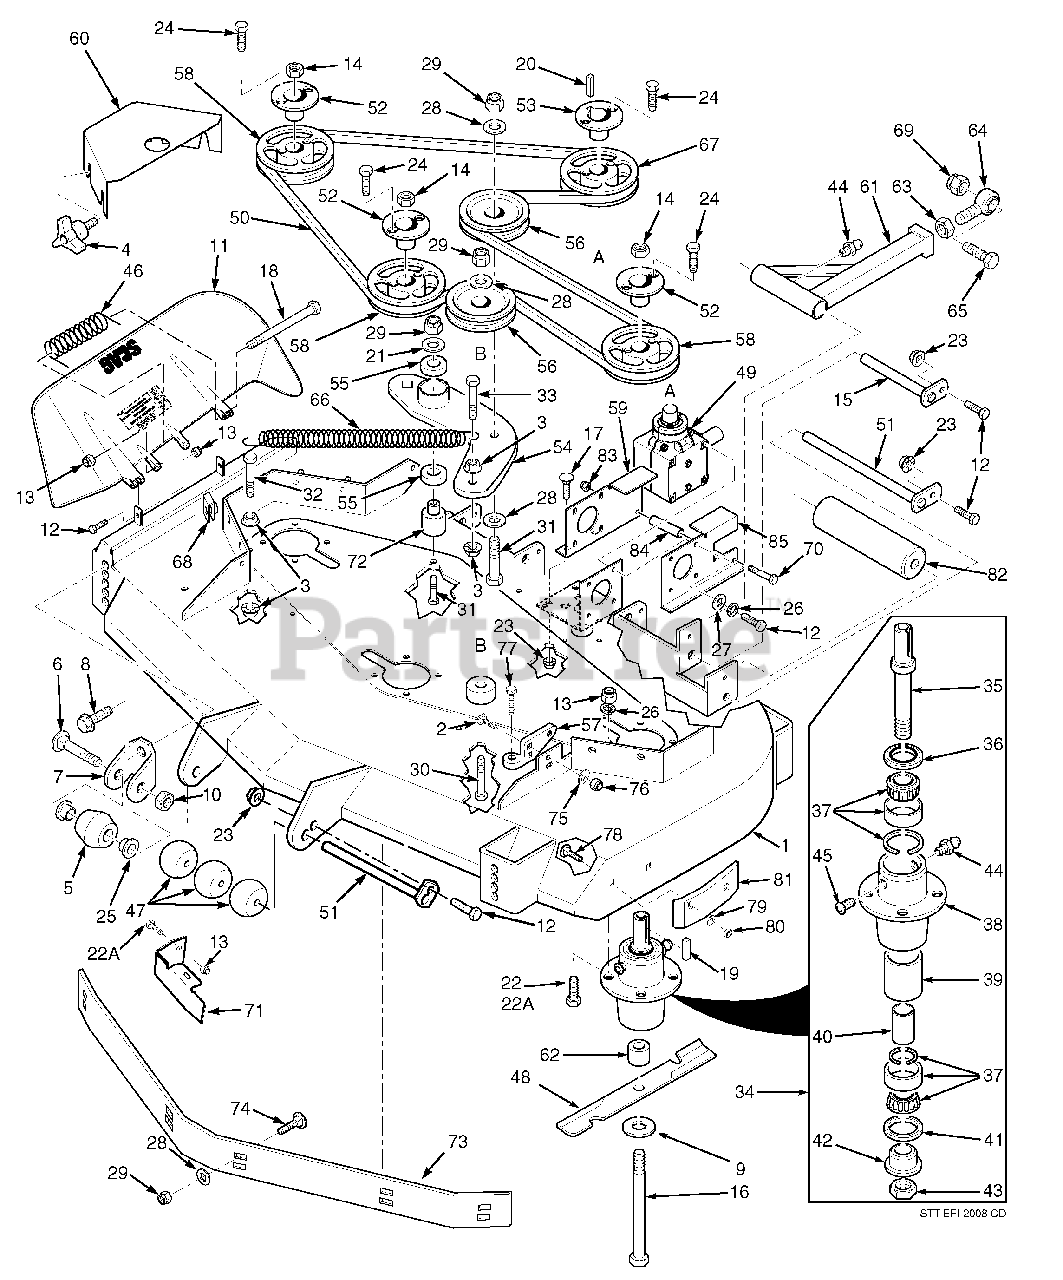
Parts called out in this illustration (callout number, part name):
1	Cutter Deck Velocity Plus
2	Bolt, Carriage 7/16-14 x 1-1/4"
3	Nut, Hex Serr. Flng. 3/8-16
4	Wing Nut, 3/8-16
5	Anti-Scalp Wheel
6	Bolt, Carriage 3/8-16 x 4"
7	Anti-Scalp Wheel Bracket
8	Bolt, Hex Serr. Flng. 3/8-16 x 1"
9	Flatwasher, 5/8" Hardened
10	Locknut, 3/8-16 Center Lock
11	Discharge Chute
12	Bolt, Hex Hd. 5/16-18 x 1-1/2" - Rear
13	Nut, Hex Elastic Stop 5/16-18 Grd. 8
14	Nut, 5/8-11 UNC
15	Pusharm Shaft
16	Bolt, Hex Hd. 5/8-11 x 9-1/2"
17	Bolt, Carriage 5/16-18 x 3/4"
18	Bolt, Hex Hd. 5/16-18 x 4-1/2"
19	Key, 1/4 x 1/4 x 2"
20	Key, 1/4 x 1/4 x 1-1/4"
21	Flatwasher,3/8 (.39 x .938 x .105") HD
22	Bolt, Hex Hd. 5/16-18 x 1-3/4"
23	Nut, Hex Serr. Flng. 5/16-18
24	Bolt, Hex Hd. 1/4-20 x 1" Grd. 8
25	Bushing, .376" I.D. Oilite
26	Lockwasher, 5/16"
27	Flatwasher, 5/16" (.375 x .875 x .083")
28	Flatwasher, 3/8" (.391 x .938 x .105")
29	Nut, Hex Elastic Stop 3/8-16
30	Bolt, Hex Hd. 3/8-16 x 3-1/4"
31	Bolt, Hex Hd. 3/8-16 x 3"
32	Bolt, Hex Hd. 3/8-16 x 1-1/2"
33	Bolt, Hex Hd. 3/8-16 x 1-1/2" Grd. 8
34	Spindle Assembly
35	Spindle Shaft
36	Seal, Top
37	Bearing Assembly
38	Spindle Housing
39	Spacer, Outside
40	Spacer, Inside
41	Seal, Bottom
42	Spindle Bushing, Bottom
43	Nut, Special 1-1/16-18
44	Grease Fitting
45	Relief Fitting, Tapered Spindle
46	Spring, Discharge Chute
47	Wheel, Anti-Scalp
48	Cutter Blade, 21"
49	Gearbox Assembly, Deck Drive
50	Belt, Cutter Deck Drive
51	Roller Shaft
52	Tapered Hub, 1-1/8" Bore
53	Tapered Hub, 1" Bore
54	Idler Arm, Cutter Deck
55	Bearings, Ball
56	Pulley, Idler
57	Lever Assembly, Deck Level
58	Pulley, 6.35" O.D. (61")
59	Mounting Plate, RH Gearbox
60	Belt, Cover
61	Pusharm
62	Spacer, Spindle Bottom
63	Nut, Hex Hd. 5/8-18 UNF
64	Rod End, 5/8" Male RH Thread
65	Bolt, Hex Hd. 5/8-11 x 4-1/2"
66	Spring, Cutter Deck
67	Pulley, 6.75 O.D.
68	U-Nut, 3/8-16
69	Nut, Hex Elastic Stop 5/8-11
70	Bolt, Hex Hd. 5/16-18 x 4-3/4"
71	Discharge Baffle 61V
72	Pivot, Idler - Short
73	Baffle, Custom Cut 61V
74	Bolt, Carriage 3/8-16 x 1"
75	Flatwasher, 7/16 (.500 x 1.25 x .083")
76	Nut, Elastic Stop 7/16-14
77	Bolt, Deck Adjust
78	Bolt, Carriage 5/16-18 x 3/4"
79	Flatwasher, 5/16"
80	Nut, Center Lock 5/16-18
81	Wear Pad
82	Wheel, Anti-Scalp
83	Nut, Elastic Stop 5/16-18
84	Spacer, Gearbox Mount
85	Mounting Plate, LH Gearbox
